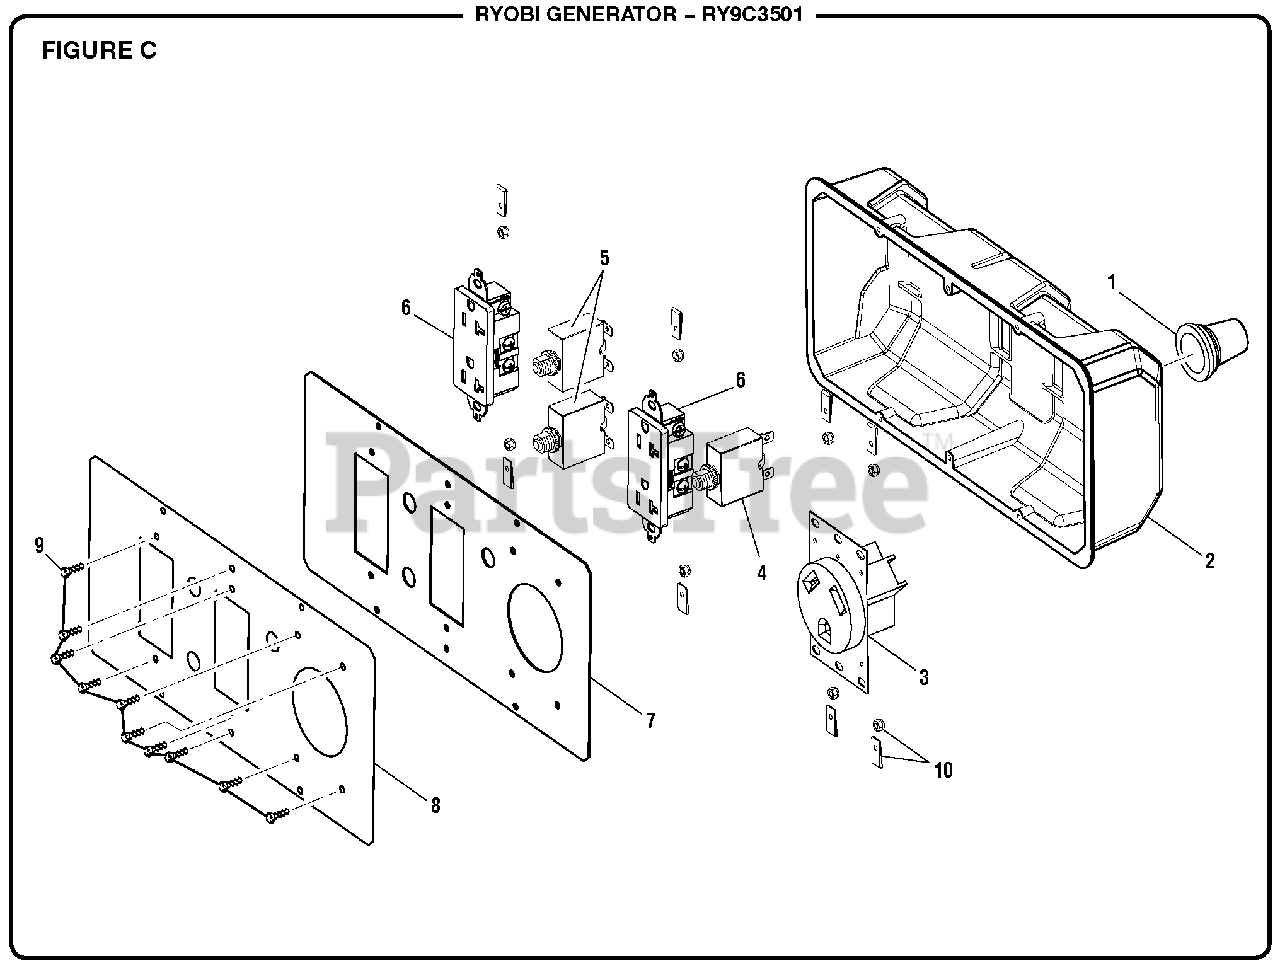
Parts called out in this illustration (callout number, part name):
1	Rubber Boot
2	Rear Control Panel
3	Twist Lock Receptacle (120 Volt, 30 Amp)
4	Circuit Breaker (30 Amp)
5	Circuit Breaker (20 Amp)
6	Duplex Receptacle (120 Volt)
7	Cover Plate
8	Electrical Panel Label
9	Screw (6-20 x .38 in., Type B)
10	Lock Nut (6-32)
